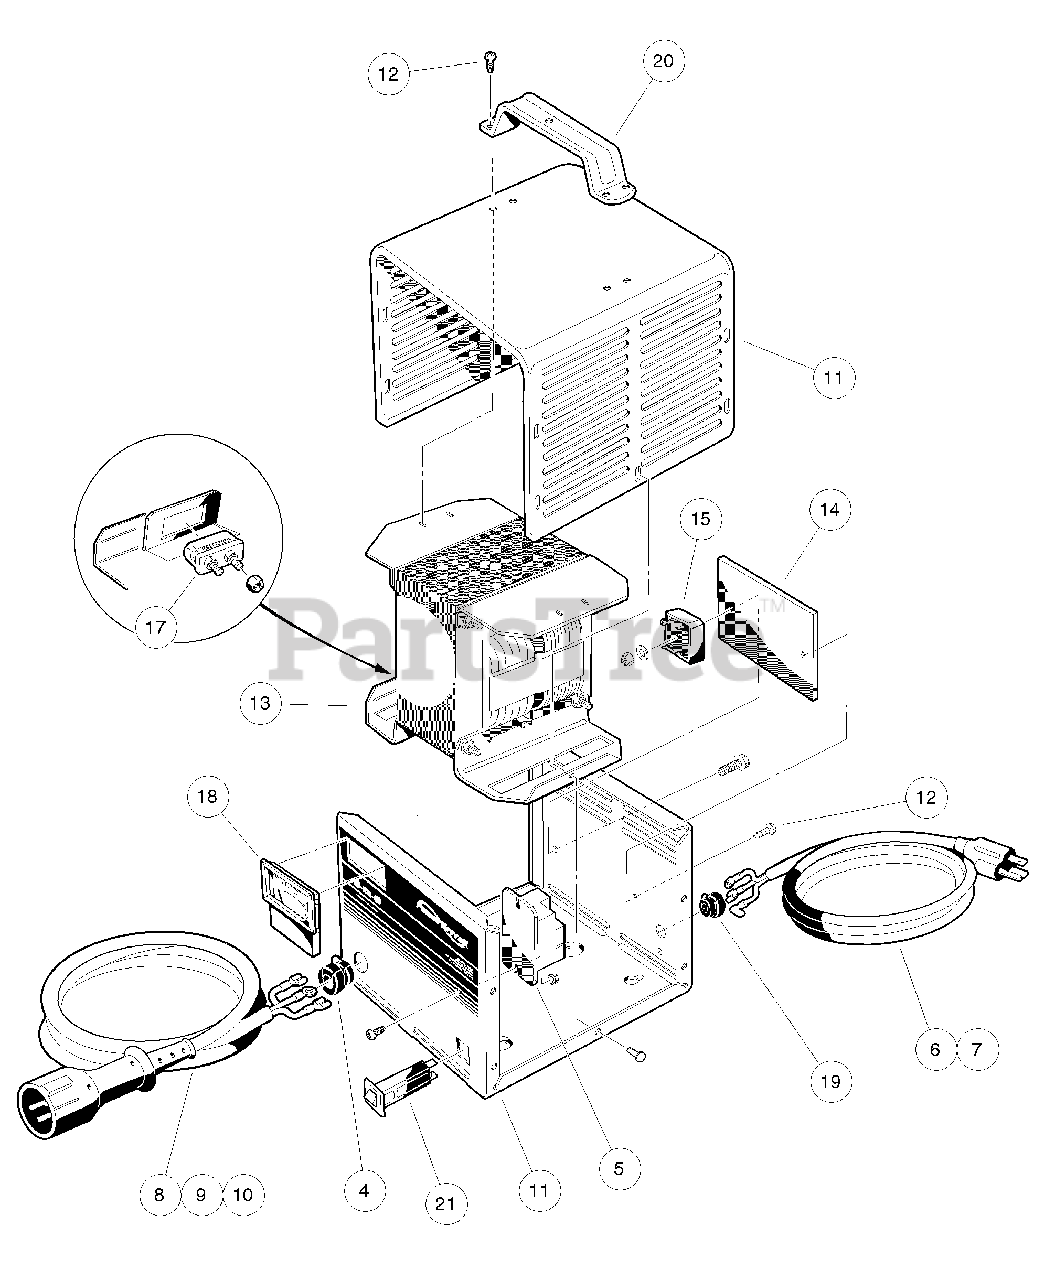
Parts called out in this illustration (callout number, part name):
4	Bushing, DC Cord
5	Relay, 48-Volt
6	Cord, AC, 80-Inch (203 cm)
7	Cord, AC, 108-Inch (274 cm)
8	PD2 DC Cordset, 113-inch
9	PD2 DC Cordset, 154-inch
10	Pd2 Dc Cordset 250 Inch
11	PD2 Case
12	Screw, #10 X 0.50 Phillips Pan-Head
13	PD2 Transformer Asm
14	PD2 Heatsink
15	PD2 Diode Bridge w/Film
17	PD2 Fuse Asm
18	PD2 Ammeter
19	PD2 AC Cord Bushing
20	PD2 Handle
21	Circuit Breaker, 15-Amp/120-Volt
